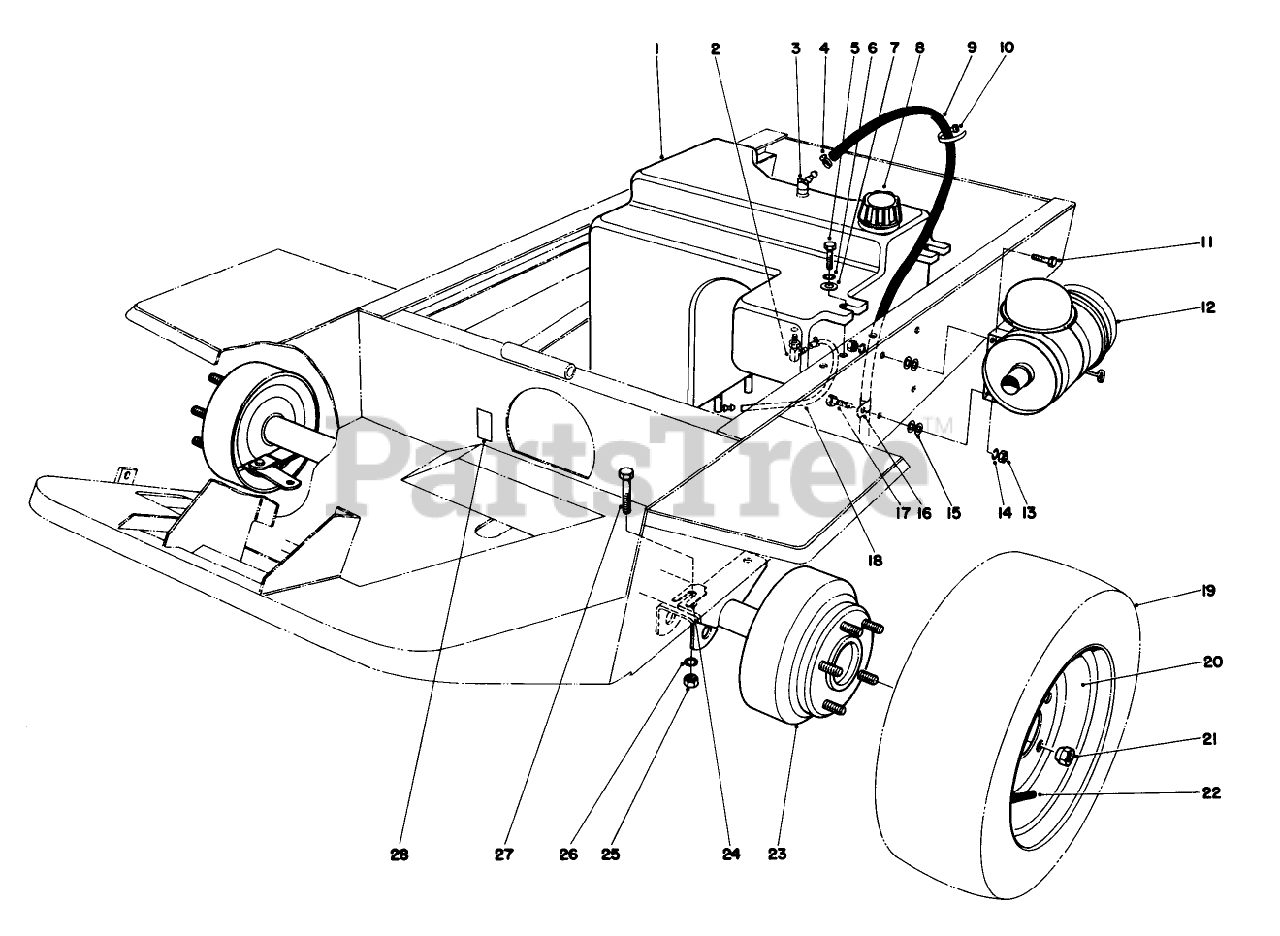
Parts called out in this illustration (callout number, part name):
1	Gas Tank (Incl. Ref. #2 & 3)
2	FITTING-ELBOW, 90 DEG
3	ELBOW
4	CLAMP-HOSE
5	SCREW-HH
6	WASHER-LOCK
7	WASHER
8	GAS CAP ASSEMBLY
9	GAS TANK VENT HOSE
10	Strap
11	SCREW-HH
12	AIR CLEANER KIT
13	NUT-HEX
14	WASHER-LOCK
15	WASHER-PLAIN
16	CLAMP-R
17	SCREW-HH
18	HOSE-FUEL
19	20 X 8.00 - 10 TIRE
20	WHEEL ASM
21	NUT-WHEEL
22	VALVE STEM AND CAP ASM
24	SHIM-AXLE
25	NUT-HEX
26	WASHER-LOCK
27	SCREW-HH
28	DECAL-OIL
